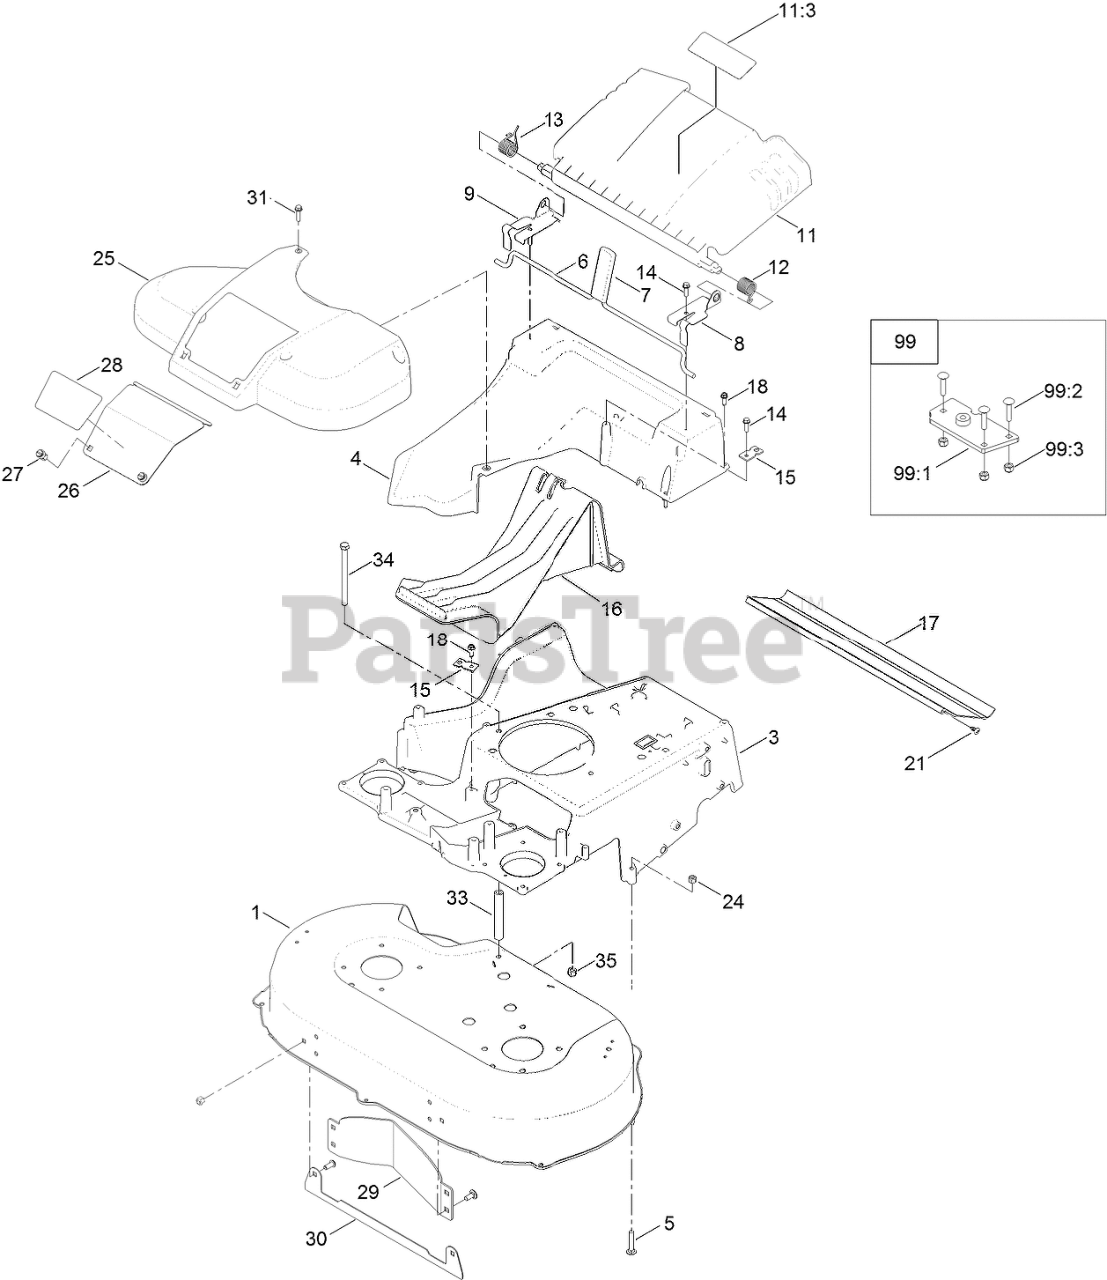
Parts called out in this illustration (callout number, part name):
1	HOUSING ASM
3	FRAME
5	SCREW-CARR
6	ROD-RELEASE, HANDLE
7	GRIP-LEVER
8	BRACKET-DOOR, LH
9	BRACKET-DOOR, RH
11	REAR DEFLECTOR ASM
11:3	DECAL-WARNING
12	SPRING-TORSION
13	SPRING-TORSION
14	SCREW-HWH
15	BRACKET-CABLE, TRACTION
16	PLUG-MULCH
17	SHIELD-TRAILING
18	SCREW-HWHTF
21	SCREW-PTH
24	NUT-LOCK, NI
25	COVER-BELT
26	DOOR-ACCESS
27	FASTENER
28	DECAL-ACCESS PANEL
29	BAFFLE-CONTROL
30	PLATE-DECK
31	SCREW-HWHTF
33	SPACER-SHIELD
34	SCREW-HH
35	NUT-LOCK, NI
99	FRAME PLATE KIT
99:1	PLATE-FRAME
99:2	SCREW-CARR
99:3	NUT-LOCK, NI
